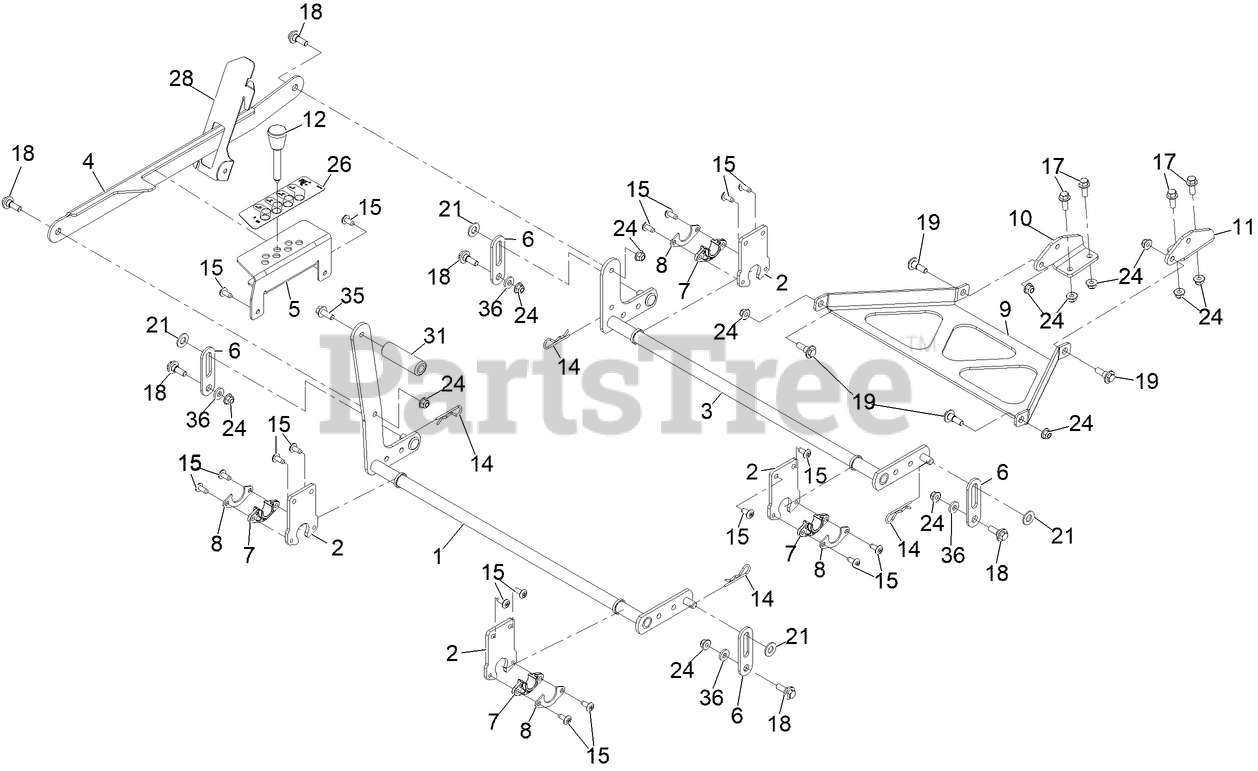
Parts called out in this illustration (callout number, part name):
1	PIVOT FRONT ASM
2	SUPPORT-CROSS, SHAFT
3	REAR PIVOT ASM
5	BRACKET-HOC
6	LINK-DECKLIFT
7	BEARING-FLANGE
8	GUSSET-DECK LIFT
9	Bracket-Strut
10	Mount-Pan, LH
11	Mount-Pan, RH
12	HOC PIN ASM
14	PIN-COTTER
17	SCREW-HHF 3/8-16 X 1
18	SCREW-SHOULDER
19	SCREW-SHOULDER, HHF
21	WASHER-FLAT
24	NUT-HF, NI
26	DECAL-HOC
28	BRACKET-HOC
31	PEDAL-FOOT LIFT
35	SCREW-HHF
